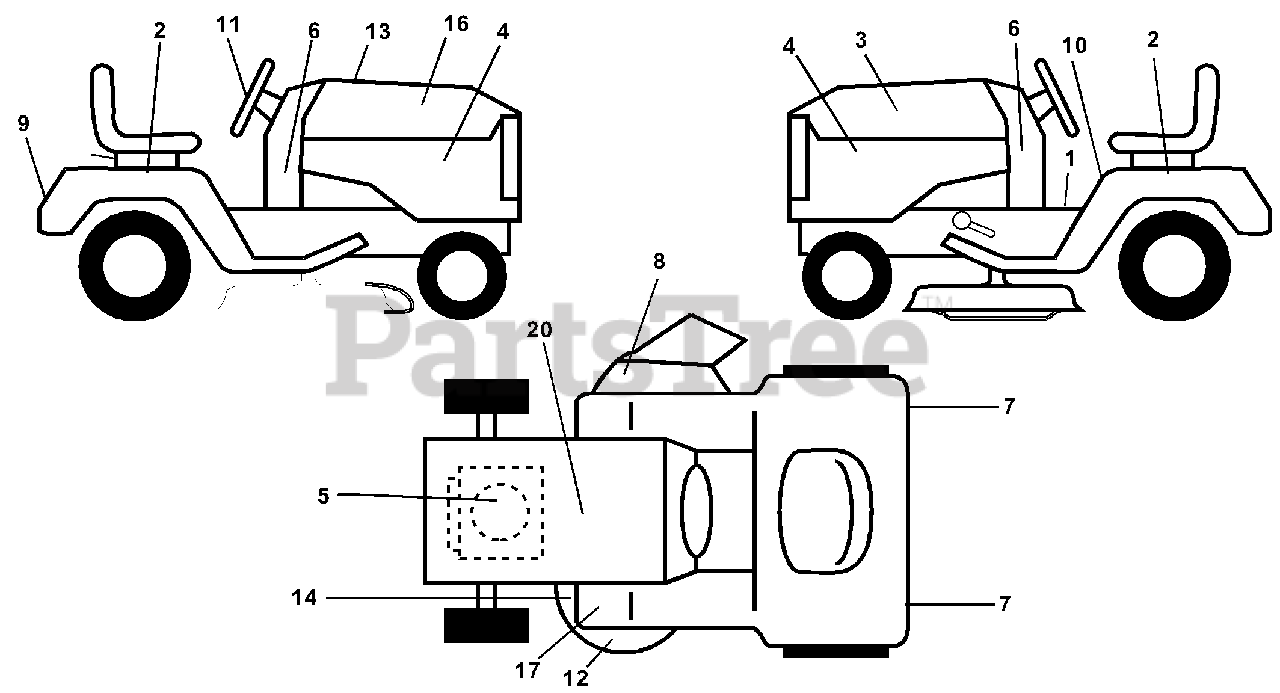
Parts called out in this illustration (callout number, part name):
1	Decal Oper
2	Decal Fender Auto
3	Decal Hood LH
4	Decal Side Panel
5	Decal HP Engine
7	Reflector Tail Light
8	Decal Warning Mower
9	Decal Fender Logo
10	Decal Fender Danger E/F
11	Decal Ins Strg Whl
12	Decal Deck Mulch/Vented
13	Decal Replacement Hood
14	Decal V-Belt Schematic
16	Decal Hood Rh
17	Decal Clutch/Bake
20	Decal Bat Dan/Psn
